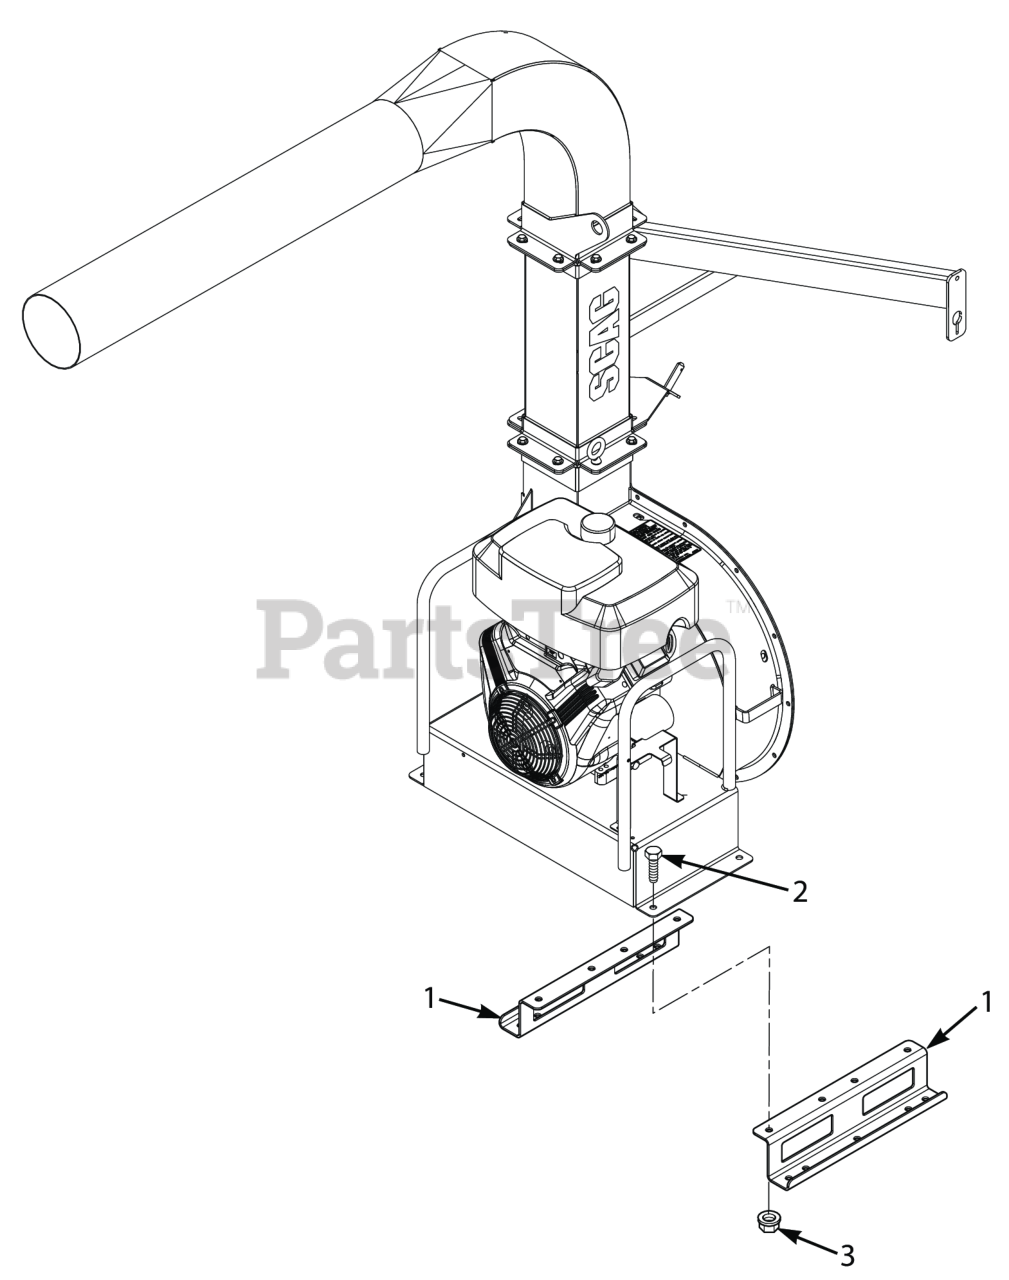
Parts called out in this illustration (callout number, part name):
1	Skid Rail - TLS
2	Bolt, Hex Head 1/2-13 x 1-1/4"
3	Nut, Elastic Stop 1/2-13
